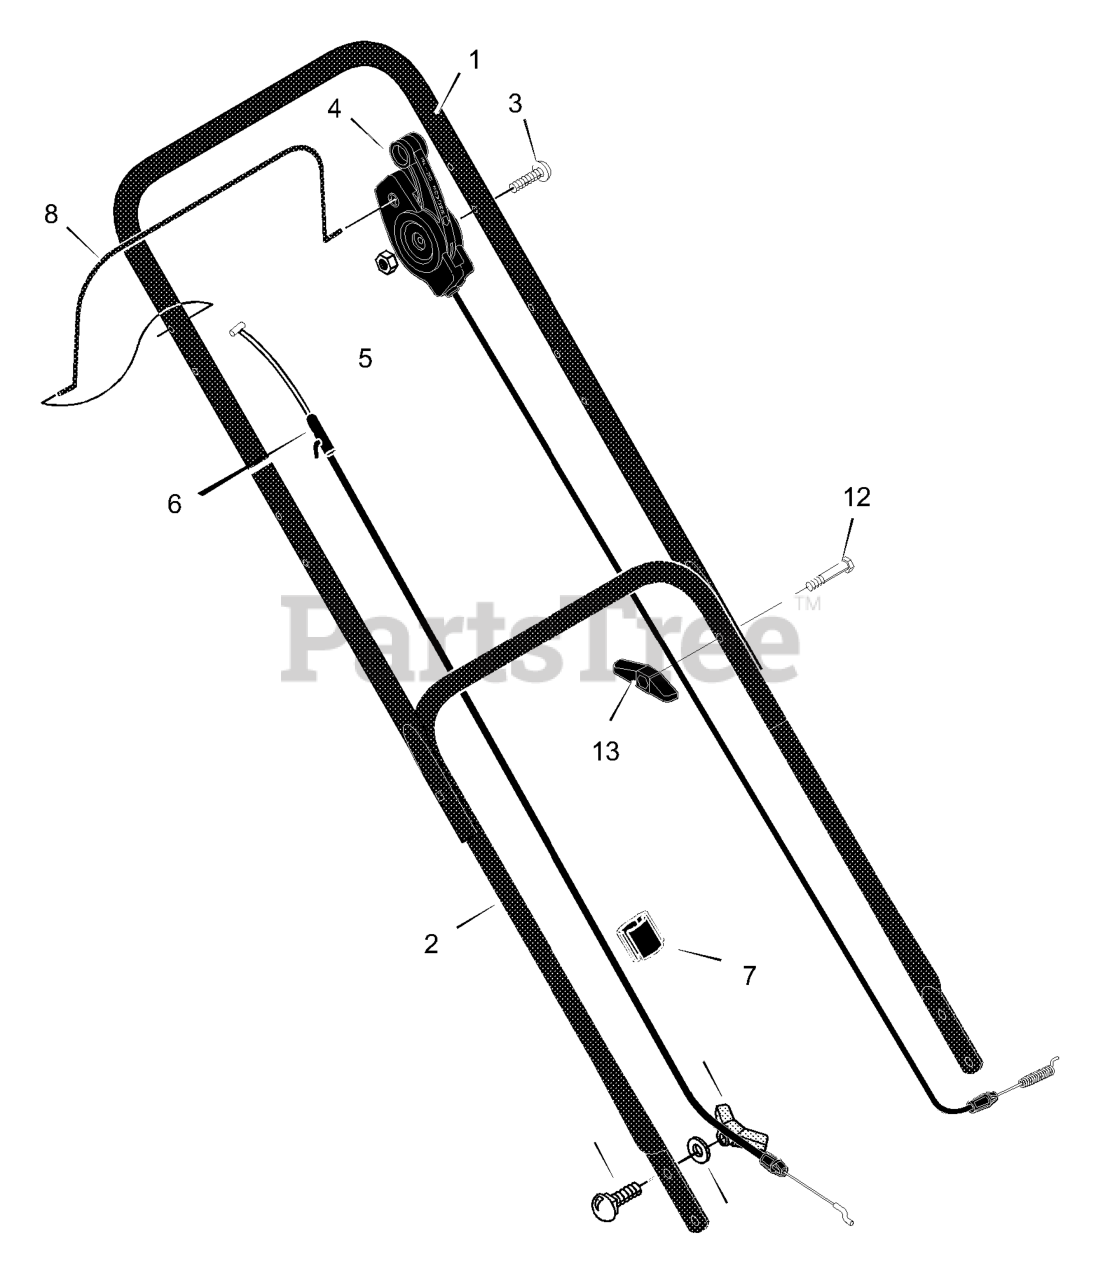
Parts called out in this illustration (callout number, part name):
1	Handle, Upper
2	Handle, Lower
4	Control, Drive
5	Locknut
6	Cable, Stop
7	Fastener, Double Cable
8	Lever, Stop
13	Knob
16	Guide, Rope
29	Bolt, Carriage
31	Knob, Plastic
